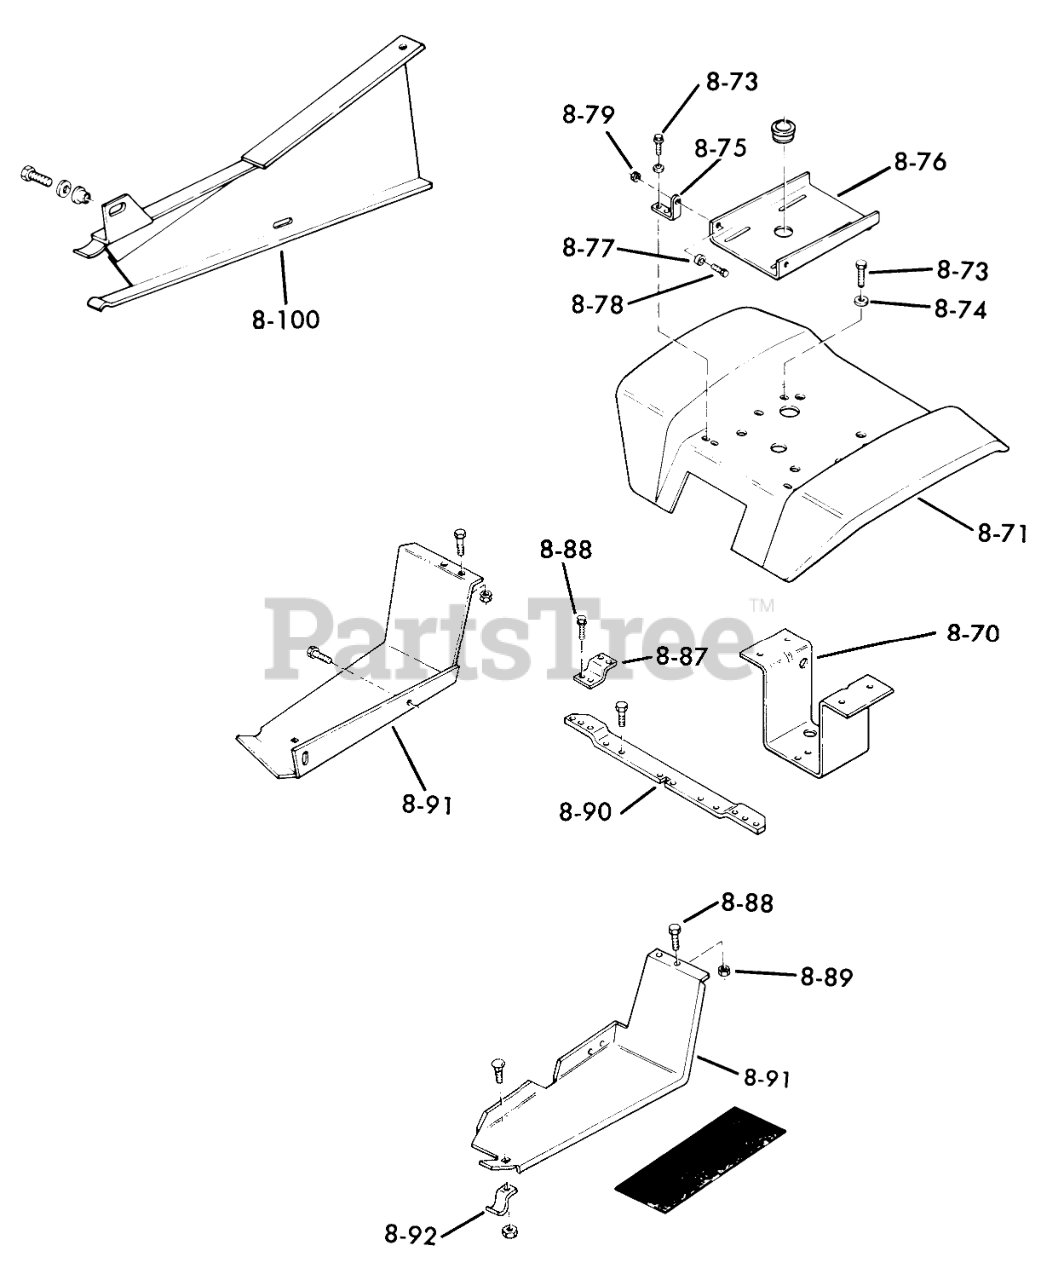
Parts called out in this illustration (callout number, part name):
8-06A	ROD-HOOD STOP
8-44	Tape
8-70	Bracket-Fender
8-71	Fender
8-73	Bolt
8-74	WASHER 5/16 SAE
8-75	BRACKET-PIVOT
8-76	Plate Seat Pivot
8-77	BUSHING
8-78	HHCS
8-79	Nut
8-87	BRACKET-FENDER R
8-88	HHCS
8-90	Bracket-Footrest
8-91	Footrest-RH
8-91	Footrest-LH
8-92	BRACKET
8-100	Belt Guard Assy
